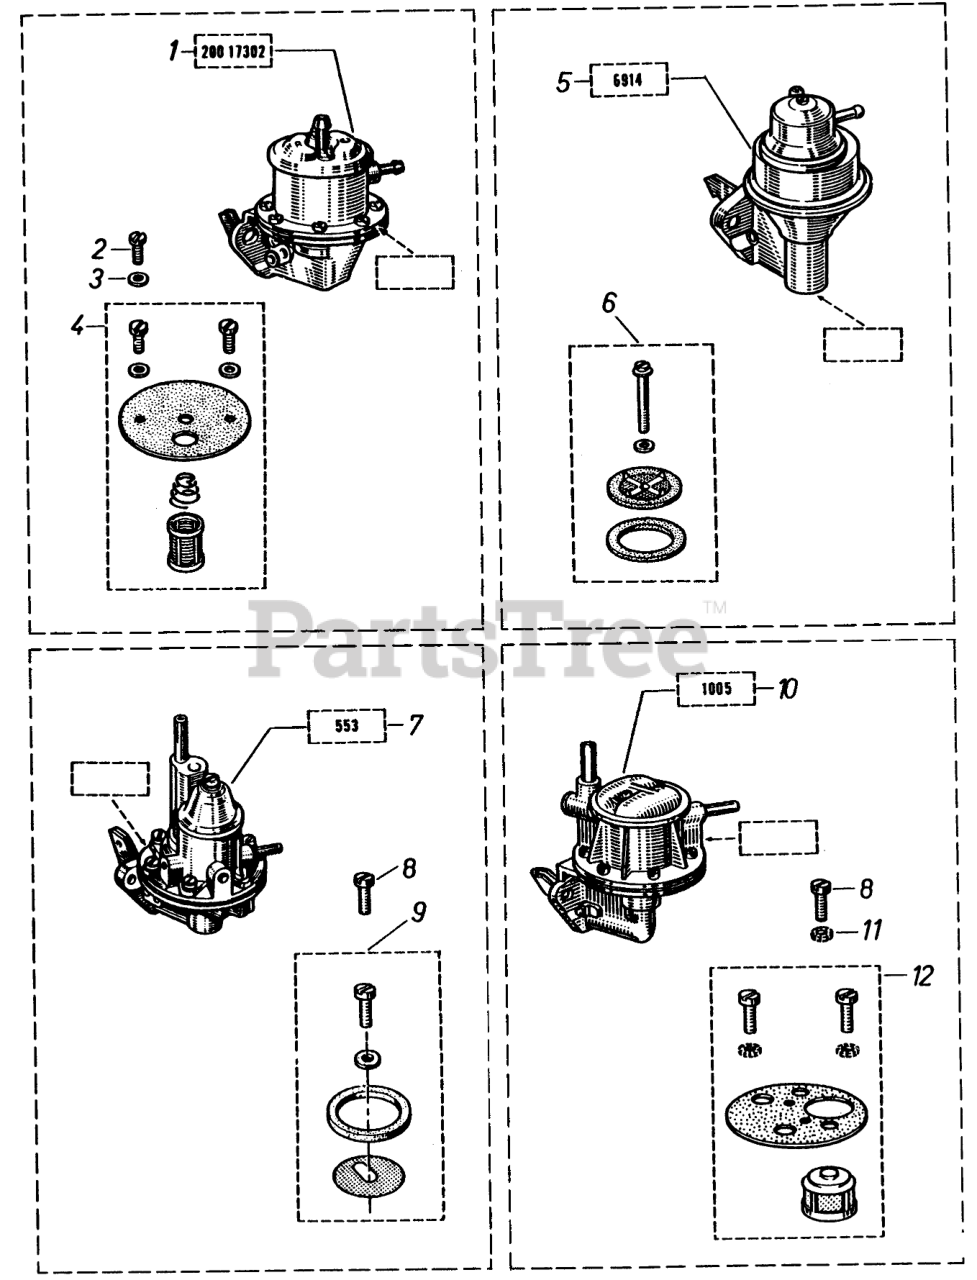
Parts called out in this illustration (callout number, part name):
5	Fuel Pump ( #6914)
6	Repair Kit (For #6914)
9	Repair Kit (For #553)
